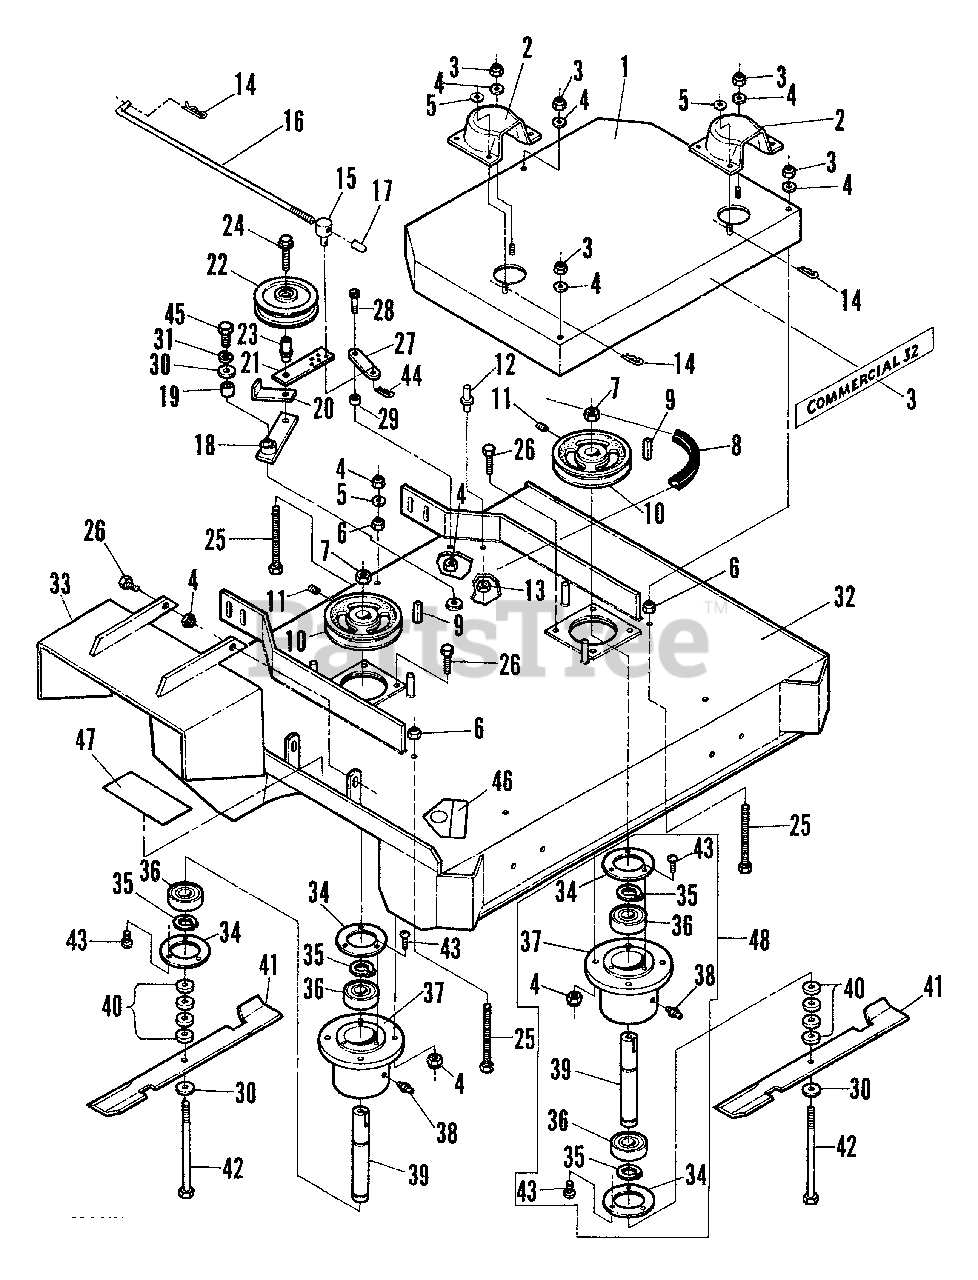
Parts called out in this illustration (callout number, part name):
1	SHIELD, Belt w/Decal 32
2	COVER, Spindle
3	DECAL, Commercial 32
4	NUT, 5/16-18 Hex Nyloc
5	WASHER, 5/16 Standard Flat
6	NUT, 5/16-18 Hex Flange Lock
7	NUT, 5/8-18 Hex
8	BELT, Engine/Blade
9	KEY, 1/4" Square x 1-1/4"
10	PULLEY, w/Set Screws
11	SCREW, 5/16-18 x 3/8" Hex Socket Set
12	STUD, Stop
13	NUT, 3/8-16 Hex Flange Lock
14	HAIRPIN, #2 Cotter
15	SWIVEL
16	ROD, Blade Drive
18	ARM, Idler w/Bushing
19	BUSHING
20	SNUBBER, Belt
21	ARM, Tightening
22	PULLEY, Idler
23	BUSHING, Flange
24	BOLT, 3/8-16 x 1-1/4" Hex Flange Lock, Grade 5
25	SCREW, 5/16-18 x 3-1/4" Hex Head Cap
26	SCREW, 5/16-18 x 1" Hex Head Cap, Grade 2
27	ARM, Blade Assist
28	BOLT, 3/8 x 3/4" Knurled Socket Head
30	WASHER, 5/8" Flat
31	WASHER, 5/8" Split Lock
32	DECK, Front 32 w/Decals
33	DEFLECTOR, Chute
34	CAP, Cutter Housing
35	RING, Snap
36	BEARING
37	HOUSING, Cutter
38	FITTING, 1/8 NPT Grease
39	SPINDLE, Cutter
40	SPACER, Blade
41	BLADE, 16-1/4" Ultra High Lift (.164)
42	SCREW, 5/8-18 x 7-1/2" Hex Head Cap, Grade 5
43	SCREW, #10-24 x 3/8" Pan Head
44	HAIRPIN, #4 Cotter
45	SCREW, 5/8-11 x 1" Hex Head Cap, Grade 5
46	DECAL, CPSC
47	DECAL, "Caution"
48	ASSEMBLY, Cutter Housing
